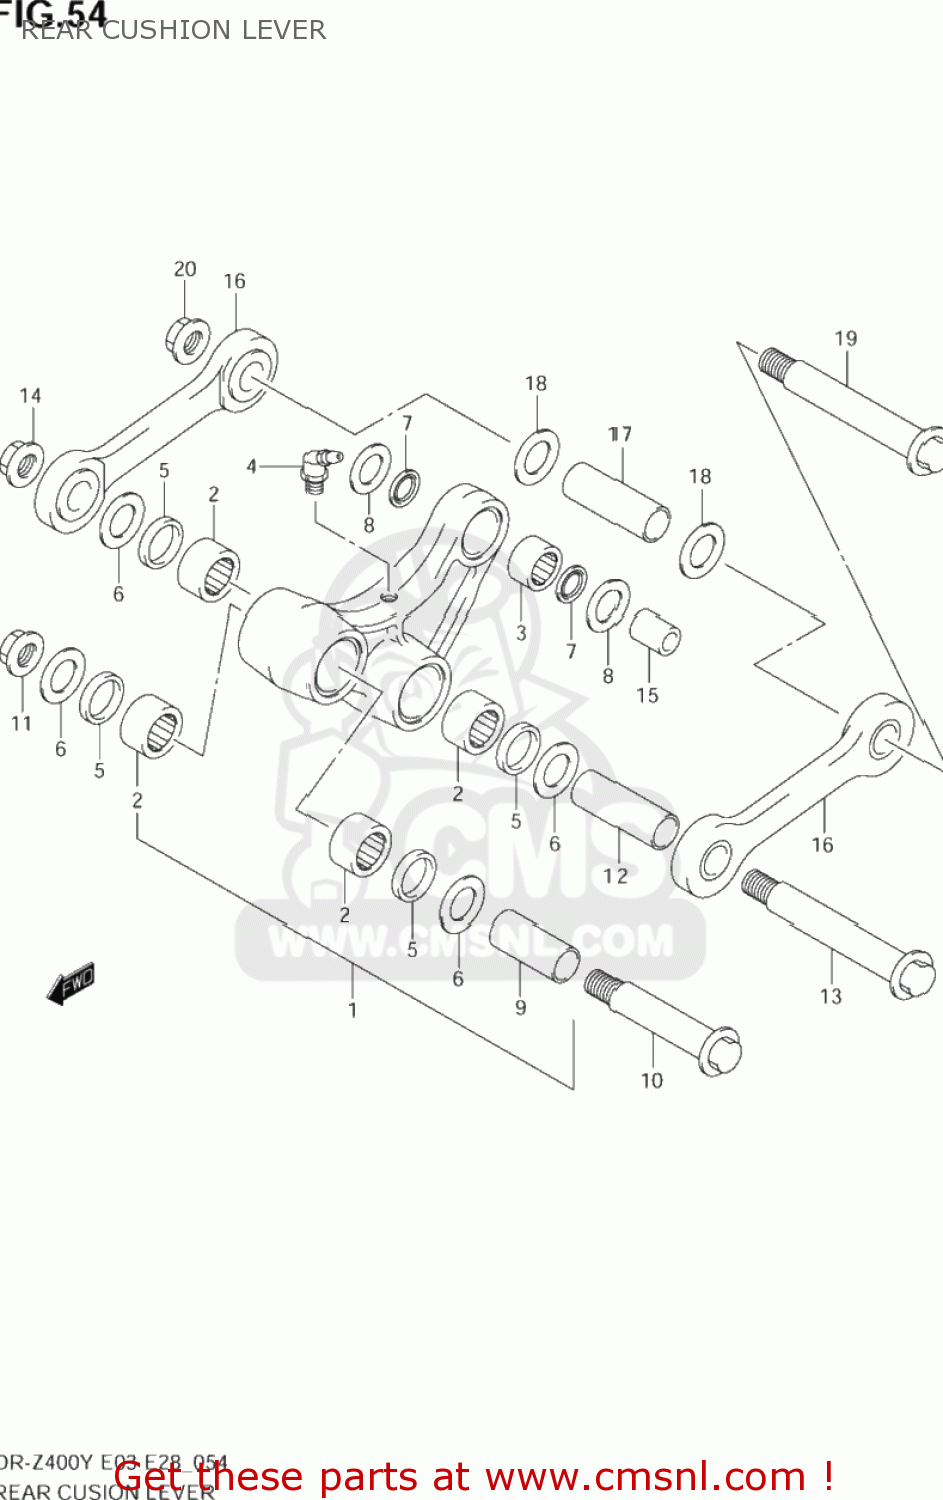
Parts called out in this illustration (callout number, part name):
1	LEVER SET,REAR CUSHION
2	BEARING(20X27X15)
3	BEARING(16X22X12)
4	NIPPLE,GREASE
5	SEAL,CUSHION LEVER DUST
6	WASHER,THRUST SWINGARM RR
7	SEAL,OIL(16X22X2.5)
8	WASHER,THRUST LVR CUSHION RR
9	SPACER,CUSHION LEVER FR
10	BOLT,RR CUSHION LEVER FR
11	NUT
12	SPACER,RR CUSHION
13	BOLT,RR CUSHION
14	NUT
15	SPACER,RR CUSHION LEVER RR
16	ROD SET,RR CUSHION
17	SPACER,RR CUSHION
18	WASHER,THRUST SWINGARM RR
19	BOLT,RR CUSHION
20	NUT
